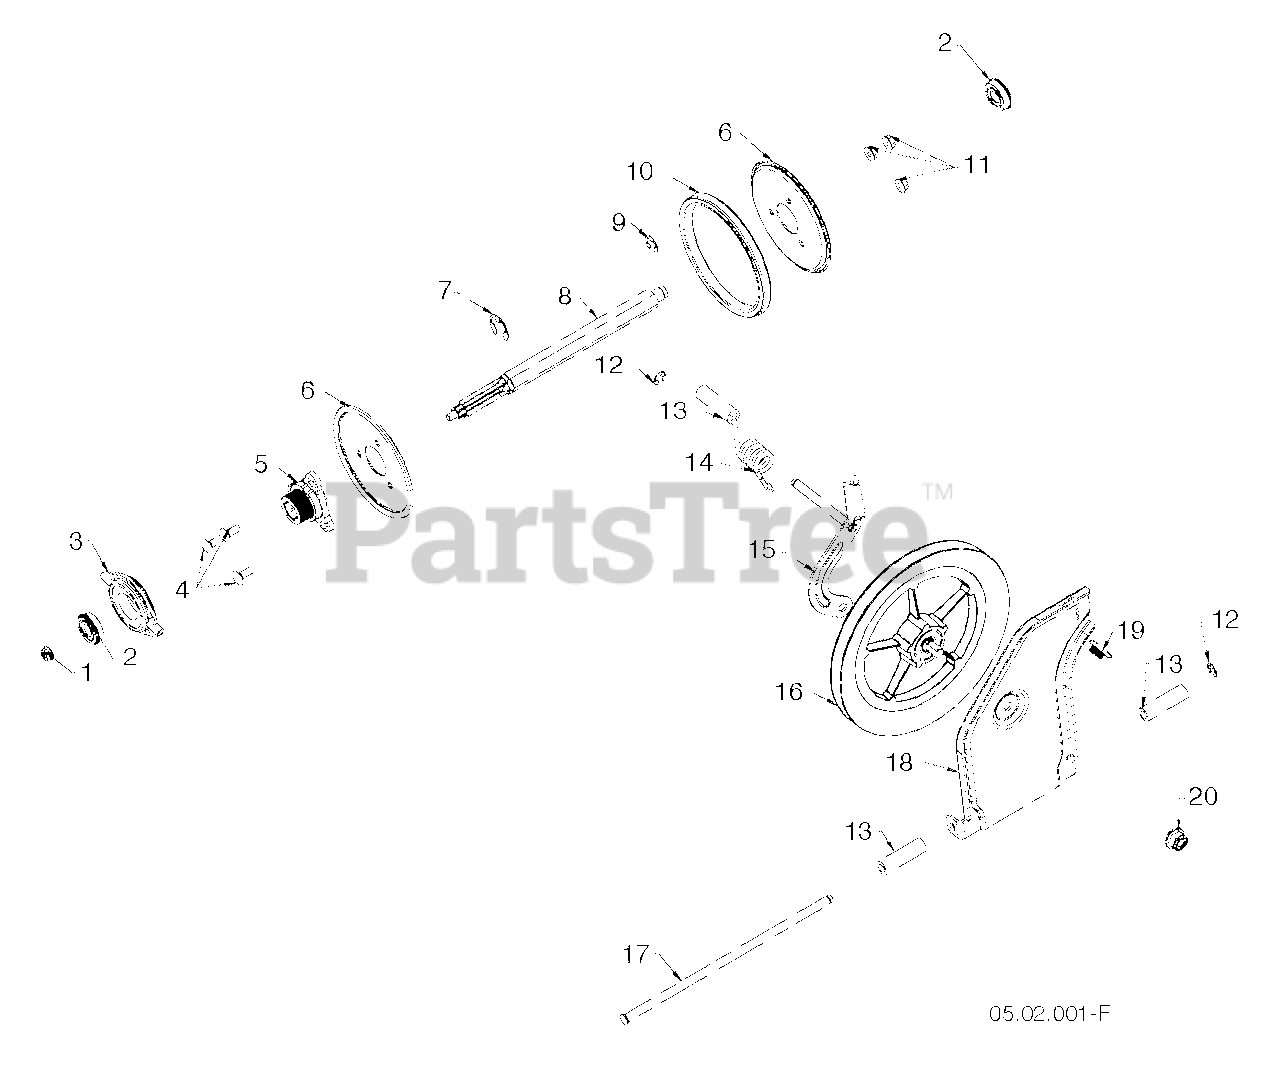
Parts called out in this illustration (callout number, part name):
1	NUT.HEX.FLANGE.LOCK.5/16-18
2	BEARING 9/16 ID. SNR
3	TRUNNION BEARING ASSY
4	BOLT.CARR.SQNK.5/16-18UNC.X3/4
5	HUB.RUBBER.WHEEL
6	PLATE.RUBBER.WHEEL.BLACK
8	SHAFT SHAFT,7T REDUCTION
9	RING RING, RETAINING RING (996
10	RING RUBBER
11	NUT.LOCK.5/16-18
12	E-RING LT
13	SPACER YOKE, TORSION SPRING
14	SPRING TORSION DRIVE
15	BRACKET.YOKE.ASSEMBLY.479
16	PULLEY.FRICTION.DISC.COMBO
17	ROD.TIP.PLATE
18	PLATE.SWING.FRICTION PULLEY.47
19	SPRING LATCH
20	NUT, 1/2-13 HEX FLG NYLOC ZD
